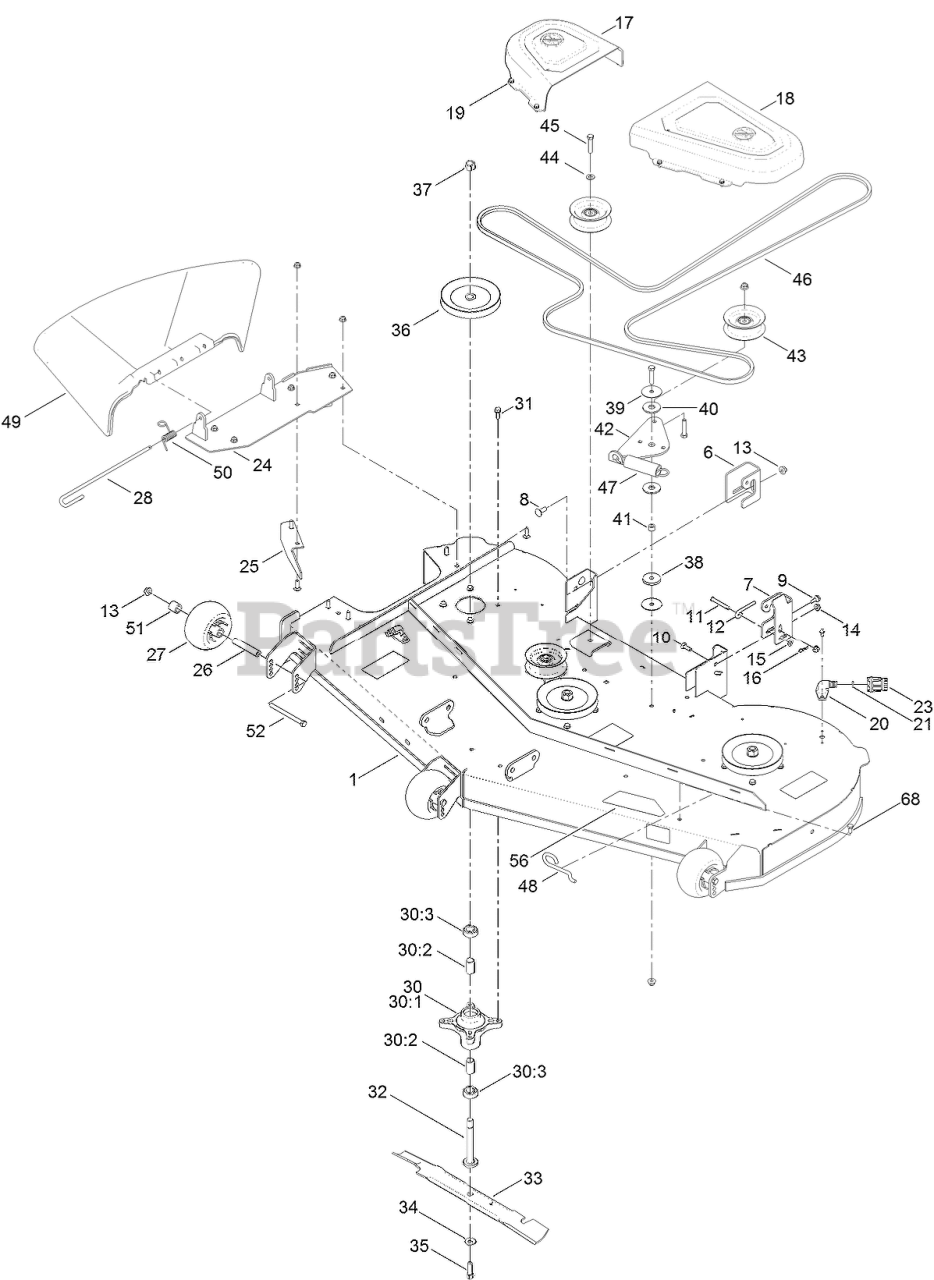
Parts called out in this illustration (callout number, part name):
1	60 INCH DECK AND DECAL ASM
6	BRACKET-HANGER, RH
7	BRACKET-HANGER, LH
8	BOLT-CARR
9	SCREW-SHOULDER, HHF
10	SCREW-CARR
11	PIN-CLEVIS
12	ROD-LEVEL, DECK
13	NUT-HF, NI
14	NUT-HF, NI
15	WASHER-PLAIN
16	PIN-COTTER
17	COVER-BELT, RH
18	COVER-BELT, LH
19	SCREW-HWH
20	FITTING-WASHOUT
21	O-RING
23	CONNECTOR-HOSE
24	PIVOT-DEFLECTOR
25	BAFFLE-CUTOFF
26	TUBE-SPANNER
27	ROLLER-SCALP, ANTI
28	PIN-CHUTE
30	SPINDLE ASM
30:1	SPINDLE
30:2	SPACER
30:3	BEARING-BALL
31	SCREW-TAPTITE
32	SHAFT-SPINDLE
33	BLADE-HI FLOW, 20.5 INCH
34	WASHER-BELLEVILLE
35	SCREW-HH
36	PULLEY
37	NUT-HEX
38	WASHER-PLAIN
39	WASHER
40	WASHER-FRICTION, COMPOSITE
41	SPACER
42	ARM-IDLER
43	PULLEY-IDLER, FLAT
44	WASHER-FLAT
45	SCREW-HH
46	BELT
47	SPRING-EXTENSION
48	HOOK-RETURN, SPRING
49	DEFLECTOR-DISCHARGE
50	SPRING-TORSION
51	SPACER-AXLE, REAR
52	SCREW-HH
68	SCREW-HH
